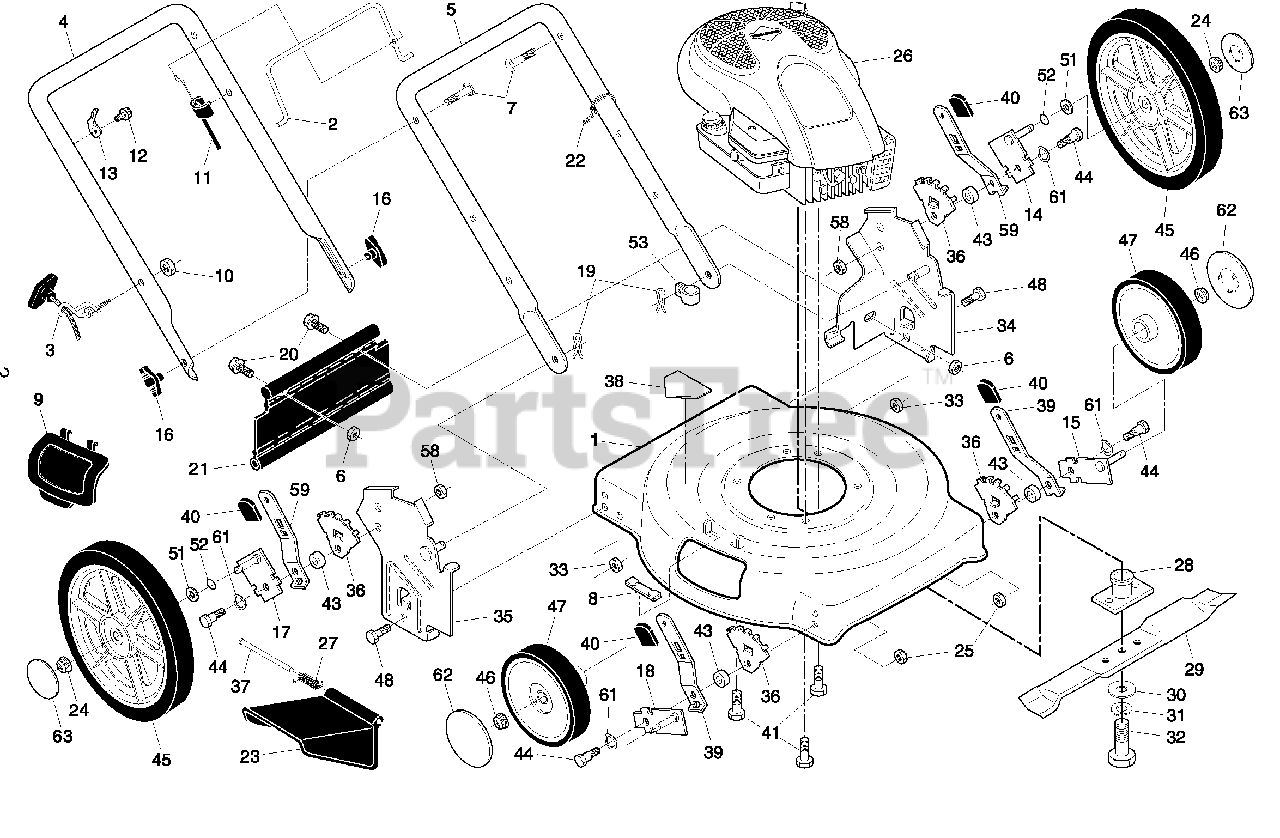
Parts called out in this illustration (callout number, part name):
1	Kit, Lawn Mower Housing
2	Control Bar
3	Rope Guide
4	Upper Handle
5	Lower Handle
6	Locknut, Hex 1/4-20
7	Handle Bolt 5/16-18
8	Clip, Closeout
9	Mulcher Plate
10	Nut, Hex 1/4-20
11	Engine Zone Control Cable
12	Hex Washer Head Screw #10-24 x 1/2
13	Up-Stop Bracket
14	Axle Arm Assembly, Rear, LH
15	Axle Arm Assembly, Front, LH
16	Knob, Handle
17	Axle Arm Assembly, Rear, RH
18	Axle Arm Assembly, Front, RH
19	Hairpin Cotter
20	Screw, Hex Cap Head 1/4-20
21	Rear Defl ector
22	Wire Tie
23	Discharge Guard
24	Nut, Hex, Flangelock 3/8-16
25	Nut, Hex, Flangelock 5/16/2018
27	Torsion Spring
28	Blade Adapter
29	22" Blade
30	Hardened Washer
31	Helical Lockwasher 3/8
32	Screw, Hex Head, Grade 8, 3/8-24 x 1-3/8
33	Nut, Hex, Nylock 5/16-18
34	Handle Bracket, LH
35	Handle Bracket, RH
36	Wheel Bracket Adjuster
37	Hinge Rod
38	Danger Decal
39	Selector Spring, Front
40	Selector Knob
41	Screw, Hex Head, Threaded, Rolled 3/8-16 x 1
43	Spacer
44	Shoulder Bolt 5/16-18
45	Wheel & Tire Assembly, Rear, 12"
46	Nut, Hex, Flangelock 3/8-16
47	Wheel & Tire Assembly, Front, 8"
48	Bolt, Hex Head 5/16-18
51	Washer, Flat 3/8
52	O-Ring
53	Clip, Cable
58	Nut, Hex
59	Selector Spring, Rear
61	Washer, Curved, Cylindrical
62	Hubcap, Front Wheel
63	Hubcap, Rear Wheel
63	Operator's Manual, English
63	Operator's Manual, French
63	Repair Parts Manual
